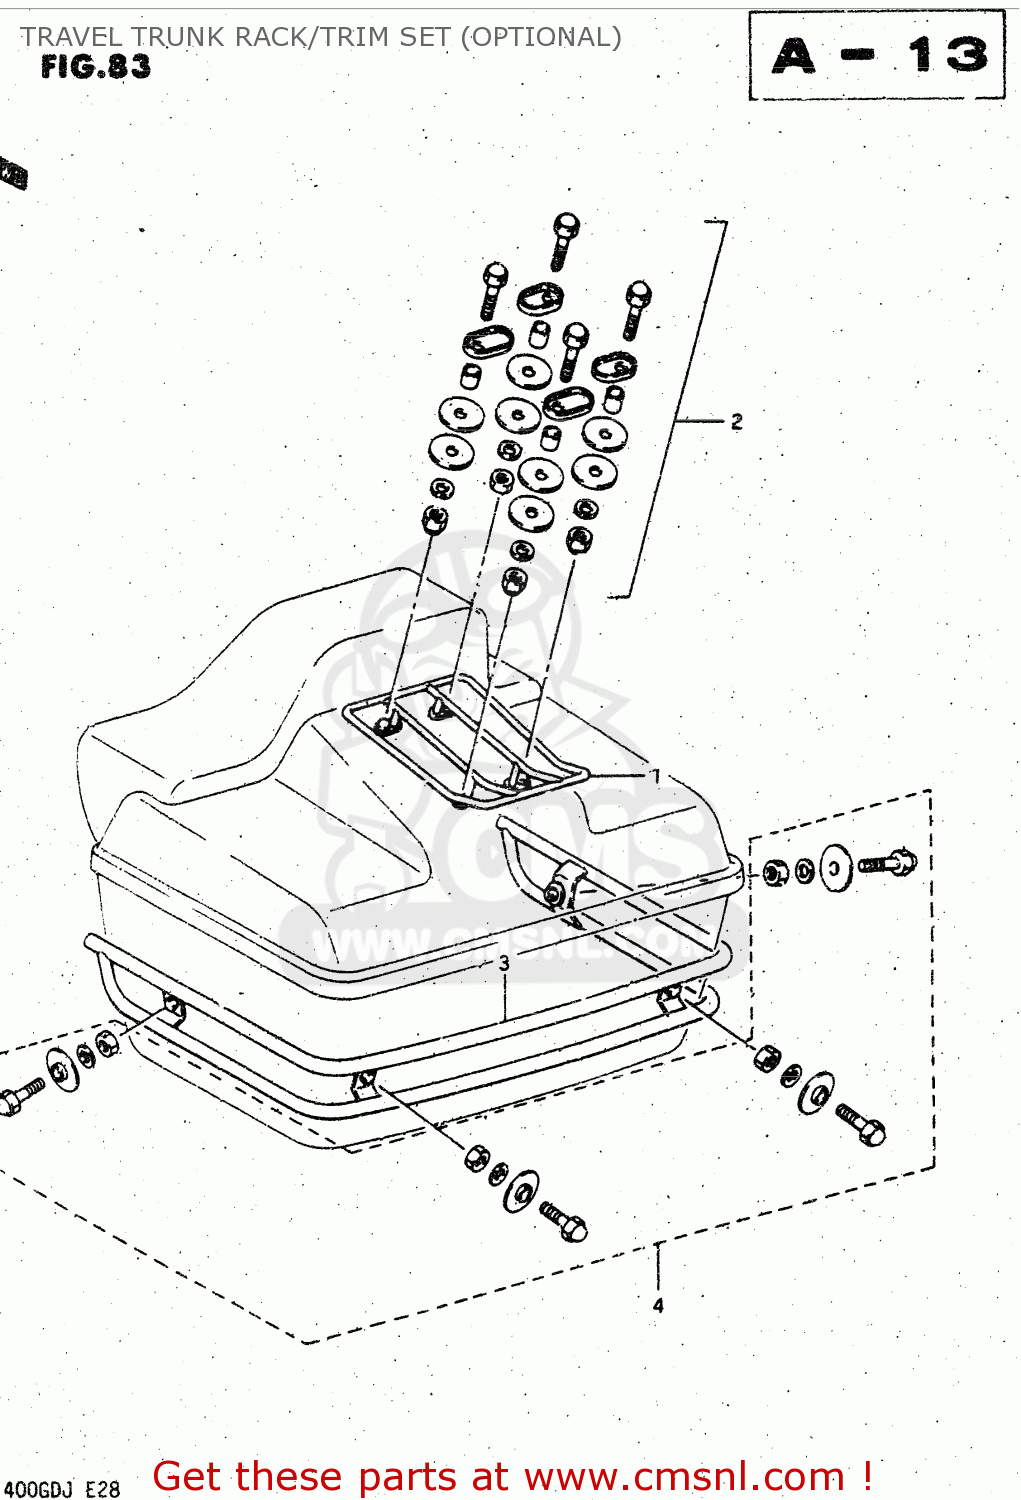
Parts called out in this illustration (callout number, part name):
1	RACK SET, TRAVEL TRUNK
2	FITTING SET, TRUNK RACK
3	TRIM SET, TRAVEL TRUNK
4	FITTING SET, TRUNK TRIM
